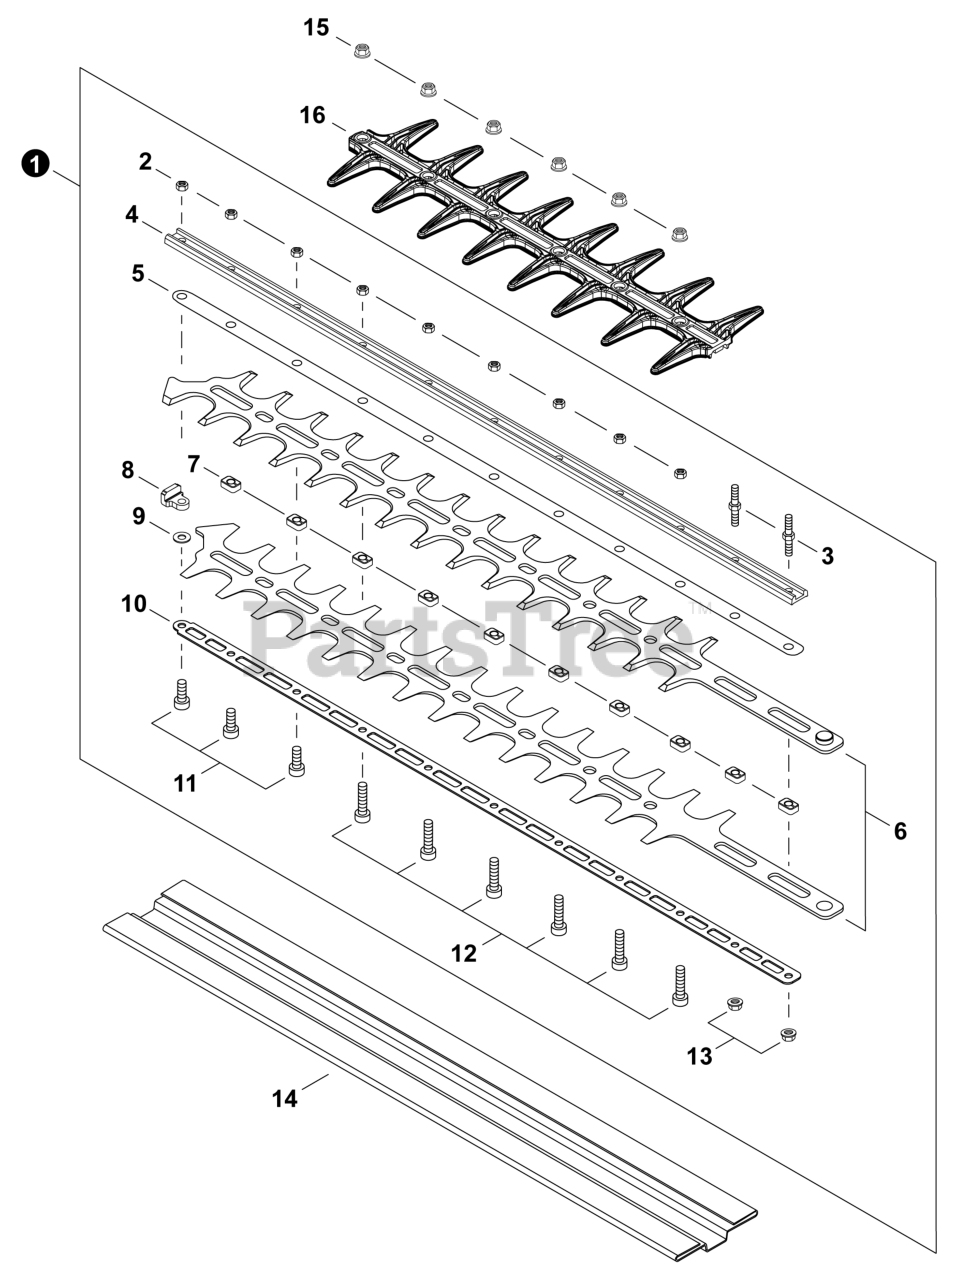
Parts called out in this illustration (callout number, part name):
1	CUTTER ASSY, 24"
3	STUD, MOUNTING M5x36
4	SUPPORT, BLADE 24"
5	SUPPORT, BLADE 24"
6	CUTTER 24"
10	SUPPORT, BLADE 24"
11	BOLT, TORX 5x16
12	BOLT, TORX 5x25
13	NUT, FLANGE M5
14	SCABBARD - RED
15	NUT, FLANGE M5
16	GUARD, CUTTER BLADE
